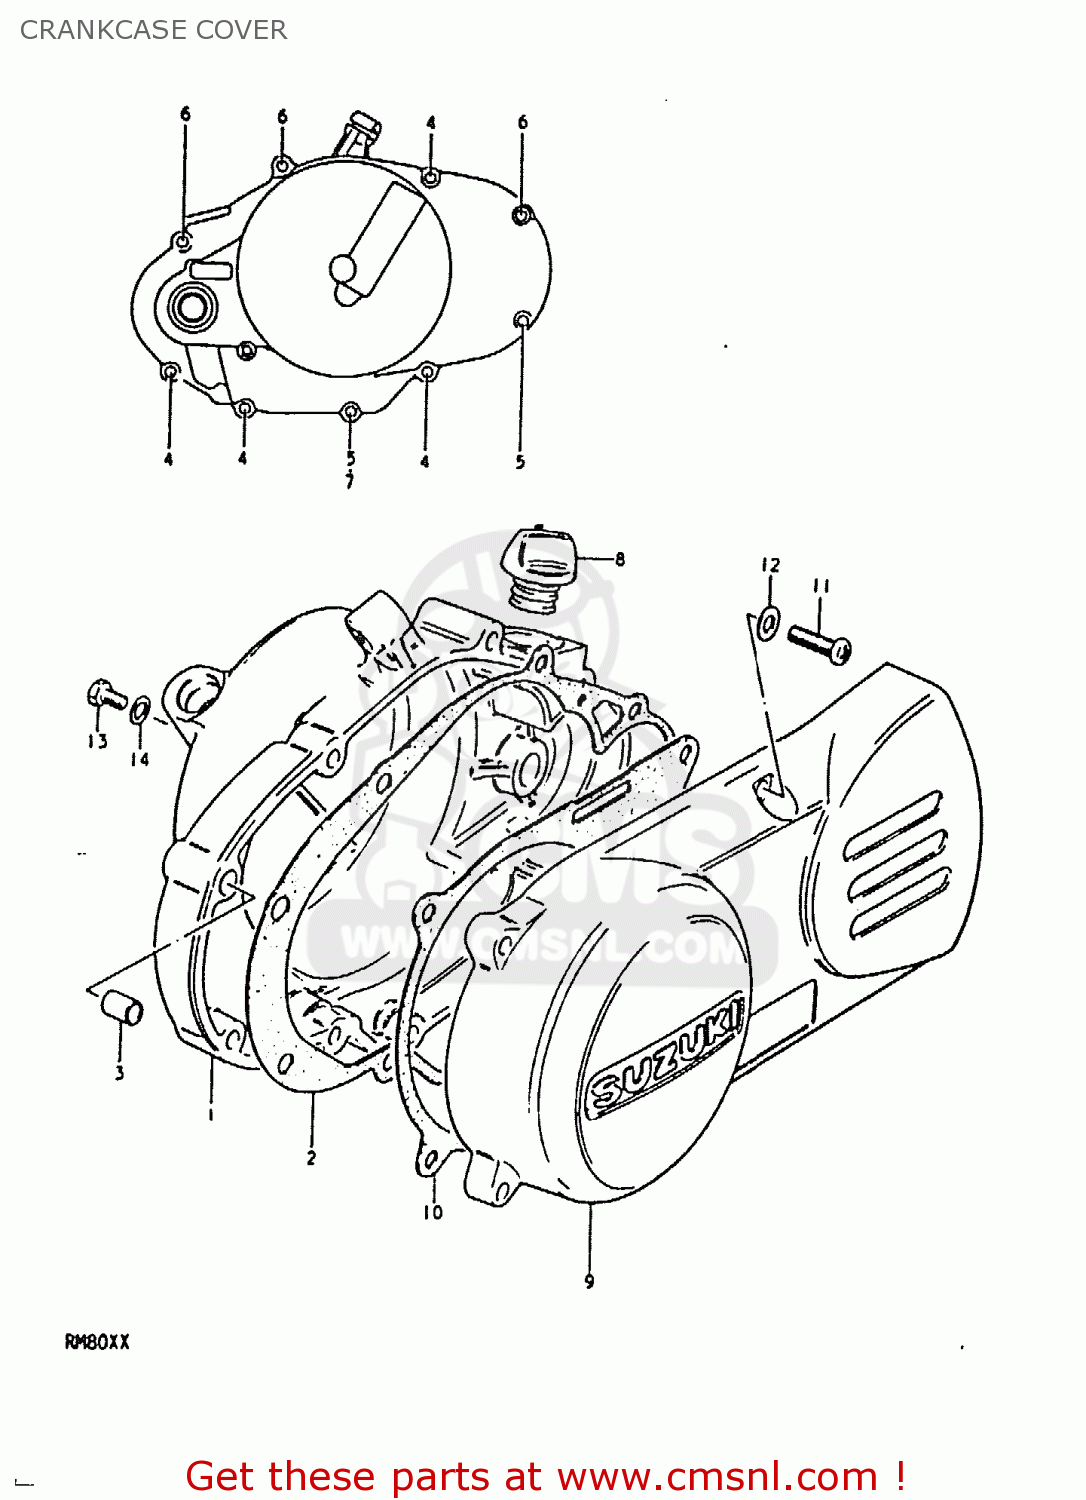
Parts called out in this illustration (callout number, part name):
1	COVER,CLUTCH
2	GASKET,CLUTCH COVER (MCA)
3	PIN
4	SCREW
5	SCREW 6X30
6	SCREW
7	GASKET(6.2X11X1).2 (NAS)
8	PLUG
9	COVER,MAGNETO
10	GASKET,MAGNETO COVER (NAS)
11	SCREW
12	WASHER
13	SCREW(6X10)
14	GASKET(6.2X11X1) (NAS)
